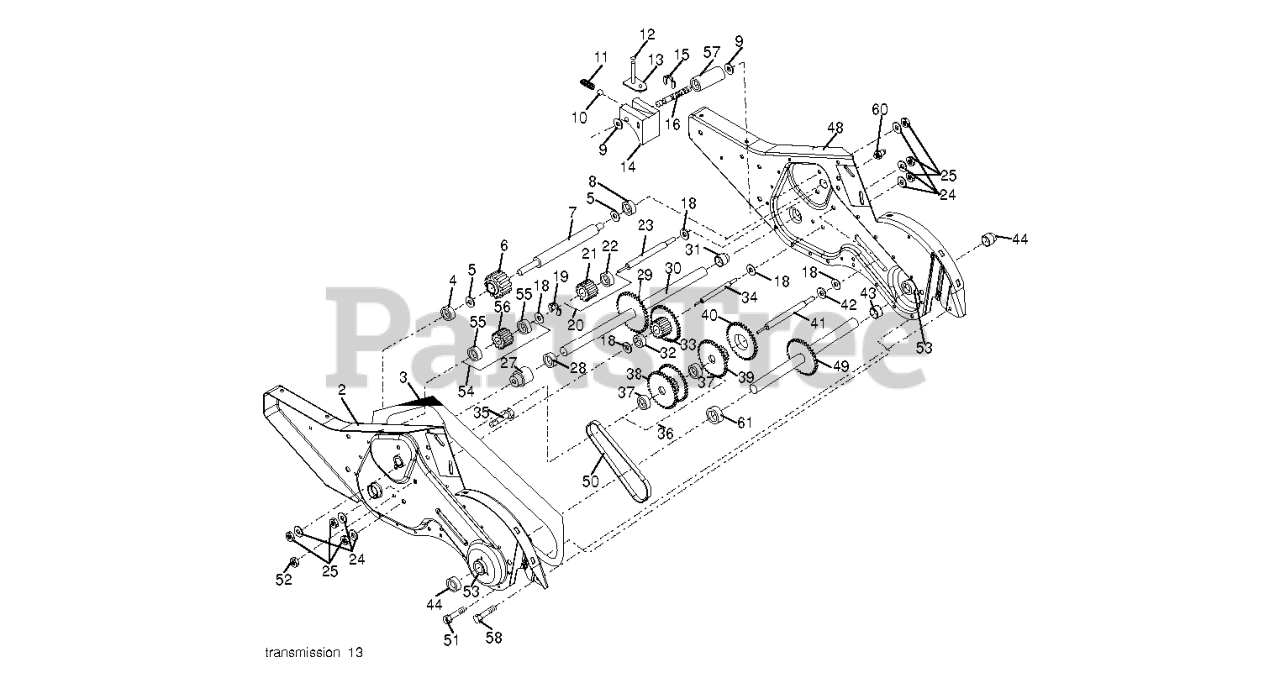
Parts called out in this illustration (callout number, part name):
1	TRANSMISSION.ASM.17
2	GEARCASE.ASM.DRT.LH.
3	GASKET.GEARCASE.CRT/DRT.TILLER
4	NEEDLE BRNG LT
5	THRUST WASHER
6	GEAR.PINION.INPUT.DRT
7	SHAFT.INPUT.D.9TEETH
9	WASHER, SEAL (2 2)
10	BALL, STEEL
11	SPRING-SHIFT CRT
13	BRACKET ASM.SHIFT.CRT
14	SHIFT FORK TI
16	SHAFT.SHIFT.DRT
20	GEAR ASSY CRT
21	GEAR-REV IDLR CRT
22	NEEDLE BEARING TI
23	SHAFT.IDLER.REVERSE.CRT
24	LOCKWASHER
25	NUT.ASF.HEX.7/16
27	BEARING, SHAFT LH CRT
30	GROUND SHAFT ASS'Y
31	BEARING, SHAFT RH CRT
33	SPRCKT 8 GEAR CRT
34	SHAFT.SECONDARY.REDUCTION.CRT
35	SCRW WHIZ LOK CRT
36	GEAR & SPROCKET.ASM.WBEARIN
37	BEARING.NEEDLE.CRT
38	ASM.GEAR & SPROCKET
39	GEAR.CLUSTER.DRT.TILLER
41	SHAFT.REDUCTION.FIRST.DRT
42	BRNG RACE T
44	SEAL ASM, OIL
48	GEARCASE.ASM.DRT.RH.
49	SHAFT.ASM.TINE
50	CHAIN.TILLER
51	SCREW
53	KIT.BEARING.TILLER.
54	GEAR.ASM.DRT.TILLER
55	BEARING.NEEDLE
56	GEAR.DRT.IDLER
57	SPACER.SPLIT
58	BOLT SHOULDER 1/4-20 UNC X.875
60	FITTING.GREASE.TAPERED
61	SPACER.1.015X1.50X.650
